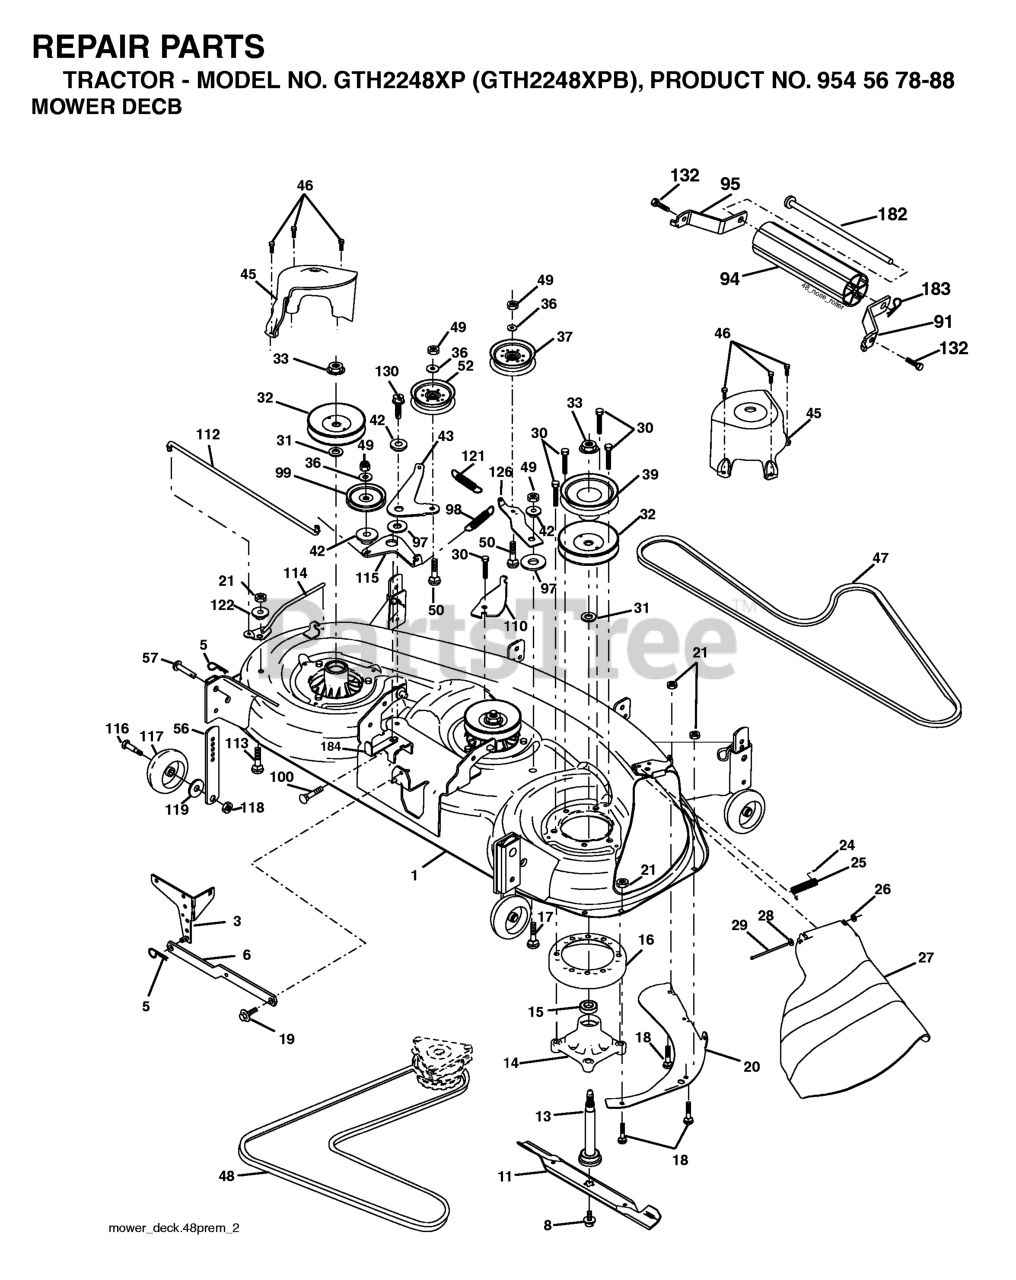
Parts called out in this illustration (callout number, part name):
1	DECK WELDMENT MOWER, 48
3	BRACKET ASM.
5	RETAINER-SPRNG RB
6	BAR SWAY DECK
8	BOLT 7/16 ASM BLADE
11	BLADE.MULCH.48"
13	SHAFT ASM W/LOWER BEARING
14	HOUSING, MANDREL 48"
16	STRIPPER.MANDREL.ROUND.BLACK
17	BOLT
18	BOLT
19	BOLT SHD 5/16-18
20	BAFFLE, VORTEX MWR
21	LOCKNUT
24	CAP-SLEEVE LT
25	SPRING, TORSION
26	NUT PUSH M
27	DEFLECTOR SUBS TO 532 180655
28	Washer 11/32 x 5/8 x 16 Ga SD
29	ROD.HINGE
30	SCREW, WASHER HEAD
31	WASHER
32	PULLEY, MANDREL
33	NUT, FLG TOPLOCK 9/16"
36	WASHER
37	PULLEY.IDLER.FLAT
39	PULLEY.DRIVEN.DECK.48'
42	SPACER RETAINER
43	ARM, IDLER SECONDARY
45	COVER.MANDREL.DECK.48"
46	SCREW.1/4-20X5/8
47	V-BELT, 48"SECONDARY
48	V-BELT PRIMARY 48"
50	BOLT.3/8-16X1.50
52	PULLEY.IDLER.FLAT.46.PR.DR.
56	BAR.ADJUST.WHEEL.ANTI.SCALP.BL
57	RIVET.PIN.HEAD.YELLOW.
91	BRKT.NOSEROLLER.RH.48"
94	NOSE ROLLER 48"
95	BRKT.NOSEROLLER.LH.48"
98	SPRING PRIMARY DRIVE
99	IDLER PULLEY
110	ARM, SPRING SECONDARY
112	LEVER, TENSION RELIEF LINK
113	BOLT.CARR.SQNK.5/16-18UNC.X3/4
114	LEVER ASM, TENSION RELIEF
115	ARM, SPRING TENSION RELIEF
116	SHOULDER BOLT
117	WHEEL GAGE DONUT
118	LOCKNUT
119	WASHER.5/16.FLAT.STE.STD.
121	SPRING.DRIVE.SECONDARY.48".DEC
122	BUSHING, PIVOT TENSION RELIEF
126	ARM, IDLER PRIMARY DECK
130	SCREW 3/8-16X1
132	SCREW, 3/8-16X3/4
182	ROD.ROLLER.NOSE.NARROW.48"
183	SPRING RETAINER
184	KEEPER BELT IDLER PLATED
